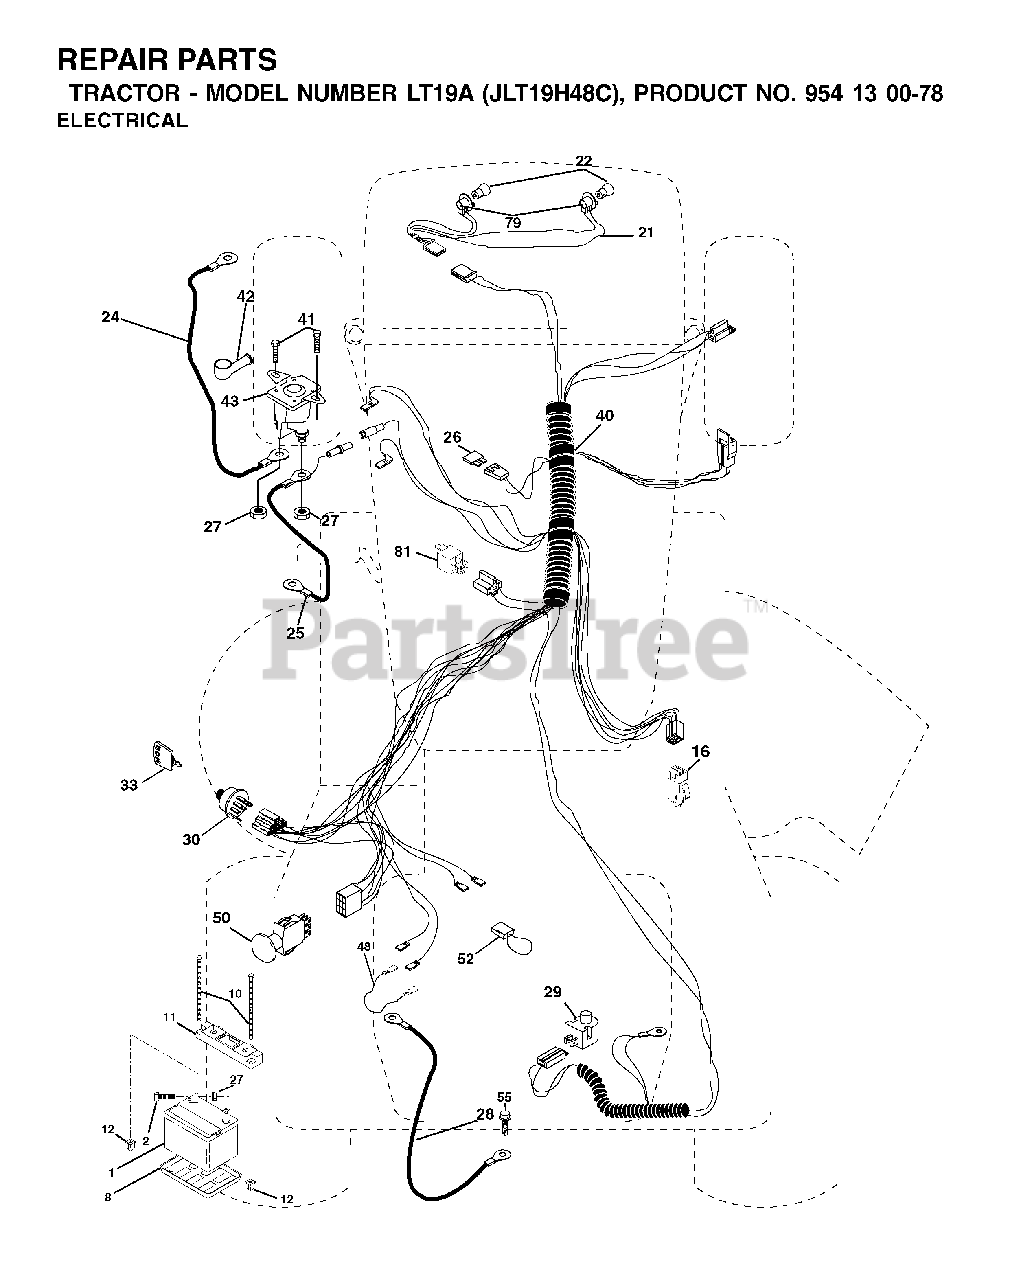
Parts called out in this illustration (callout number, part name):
1	BATTERY 12V .35 AMP
8	BATTERY TRAY T
10	BOLT 1/4-20 X 7.5
11	BATTERY HOLDDOWN
12	NUT, PUSH NYLON 1/4" BATTERY
16	SWITCH INTERLOOK PUSH-IN
21	HARNESS.W/LIGHT SOCKET
22	LIGHTBULB
25	CABLE BATTERY 6 GA 22" W/16W
26	FUSE 20AMP
27	NUT
28	CABLE GROUND 6 GA 21" 90T BLK
29	PLUNGER SWITCH (COLOR:OLIVE)
30	IGNITION SWITCH
33	KEY MLD GEN DELTA
41	SCREW
42	TERMINAL COVER
43	SOLENOID
50	PTO SWITCH
52	WIRE PROTECTION LOOP
55	SCREW LT
79	BULB HOLDER ASM.
81	RELAY.ASSY.T
